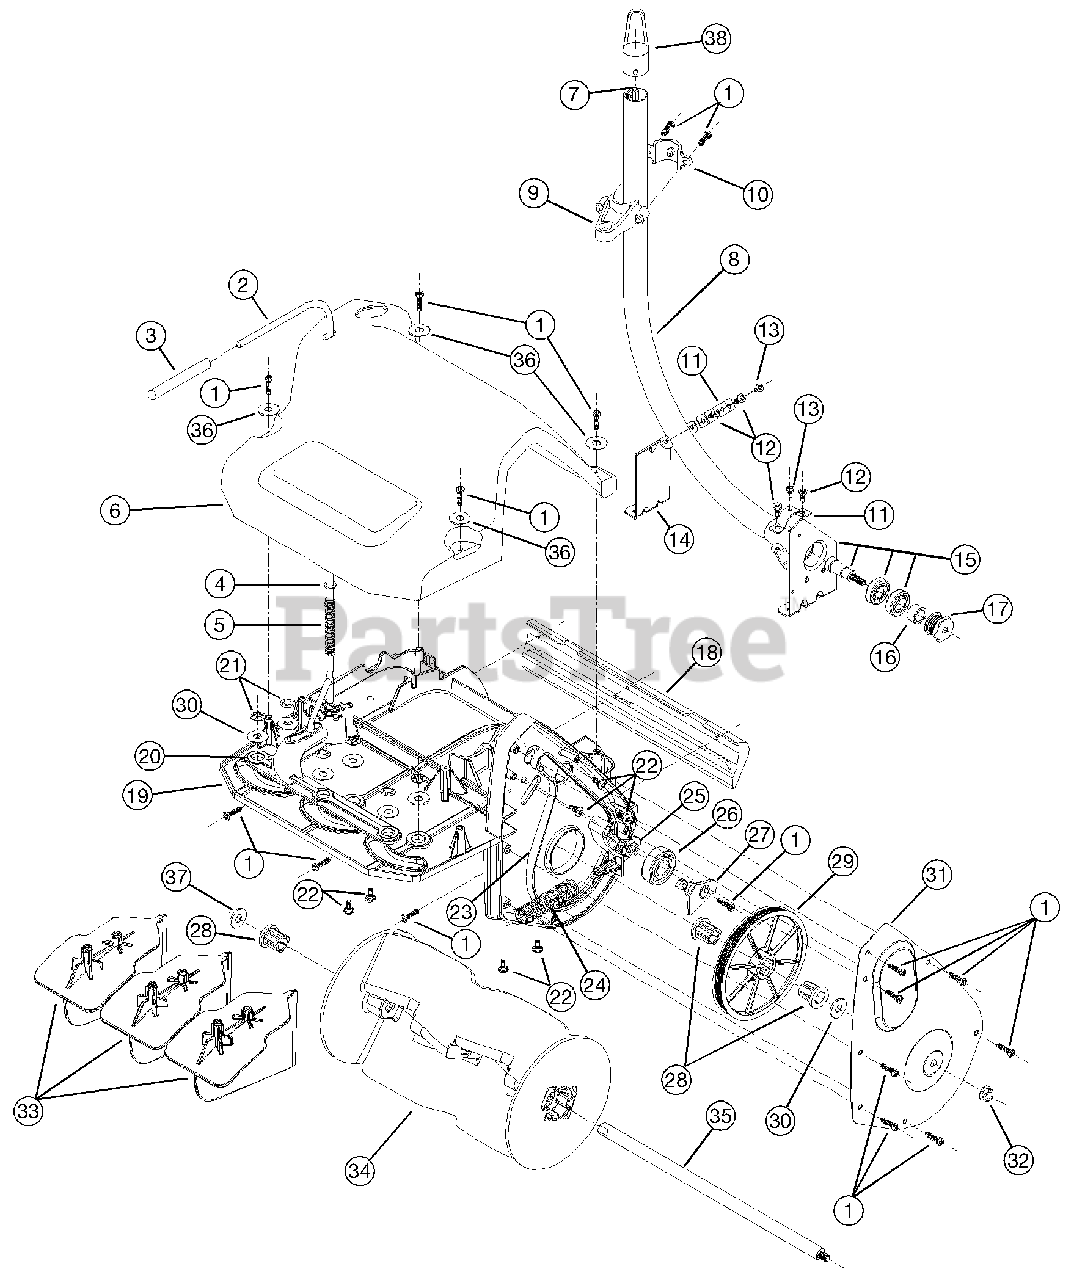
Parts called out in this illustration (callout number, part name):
2	Vane Control Handle
4	Washer
5	Spring
6	Cover
7	Flex Shaft
8	Drive Shaft Assembly
9	Clamp, LH
10	Clamp, RH
13	Screw, Anti-rotation
14	Drive Housing Bracket, RH
15	Drive Housing Bracket, LH
16	Spacer
17	Drive Pulley
18	Scraper
19	Snow Thrower Housing
20	Vane Control
21	Pushnut
23	Drive Belt
24	Spring
25	Idler Arm
26	Ball Bearing
27	Keeper
28	Flange Bearing
29	Driven Pulley
30	Washer
31	Belt Case Cover
32	Flange Lock Nut
35	Rotor Shaft
38	Hanger Accessory
